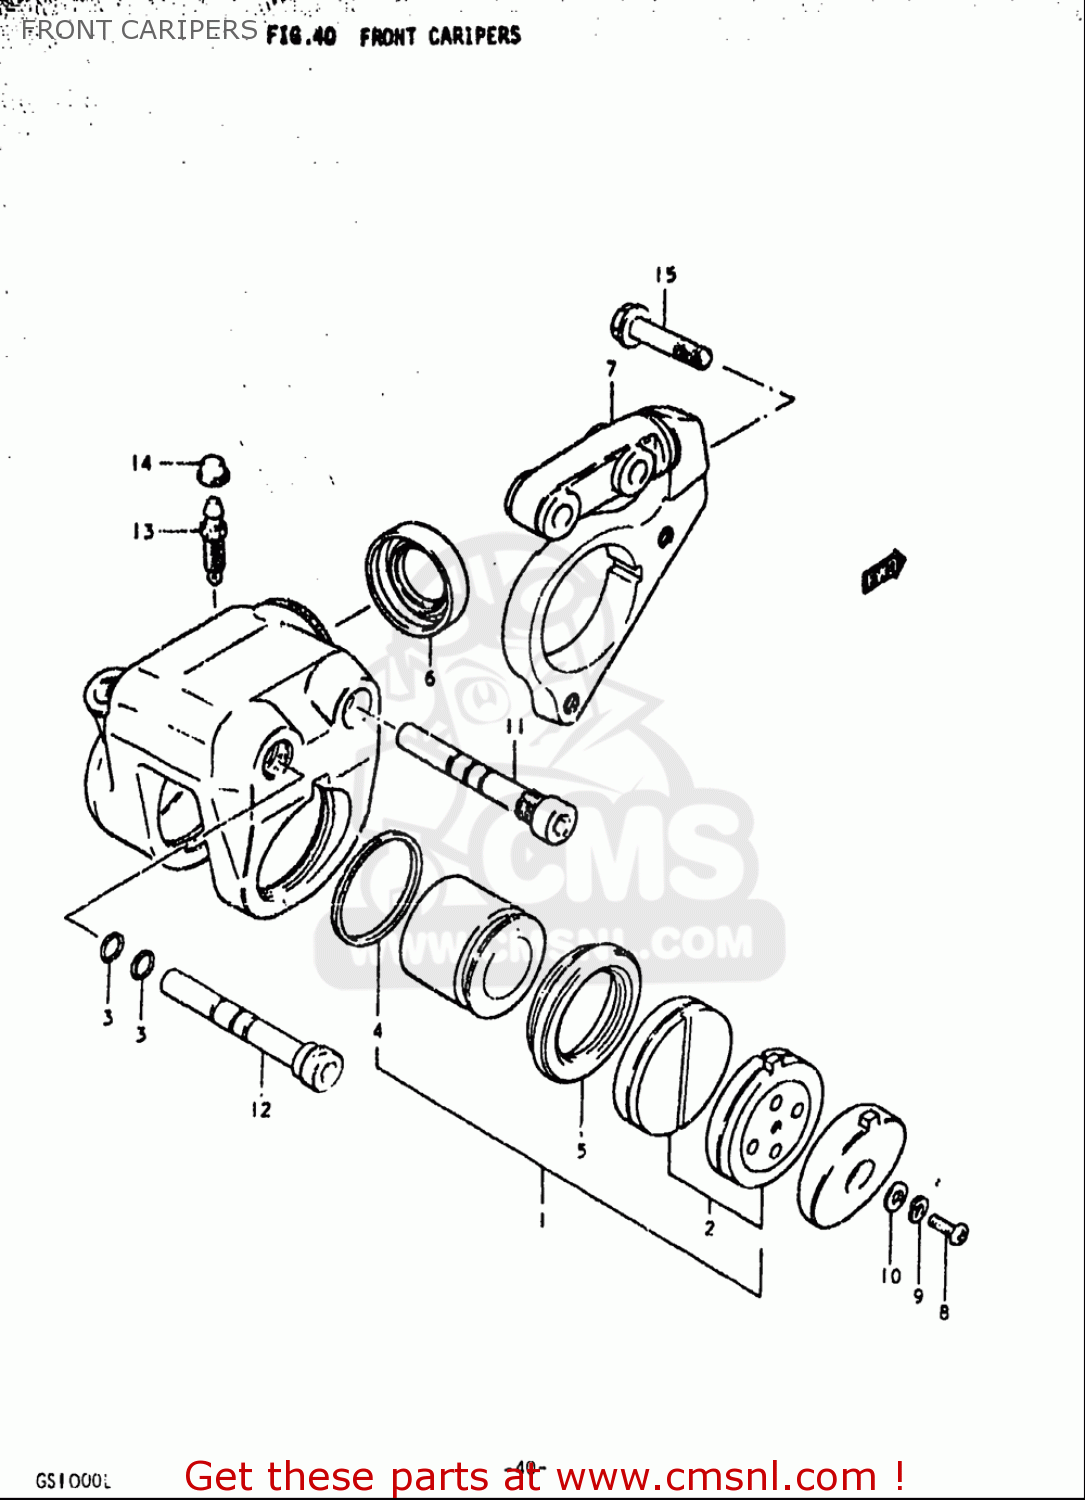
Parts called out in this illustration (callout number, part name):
2	PAD SET (NAS)
3	O RING,AXLE CALIPER
4	SEAL,PISTON
5	BOOT,PISTON
6	BOOT,HOLDER
8	SCREW
9	WASHER,LOCK
10	WASHER
11	AXLE,CALIPER
12	AXLE NO.2
13	BREATHER
14	CAP,BLEEDER PLUG
15	BOLT
